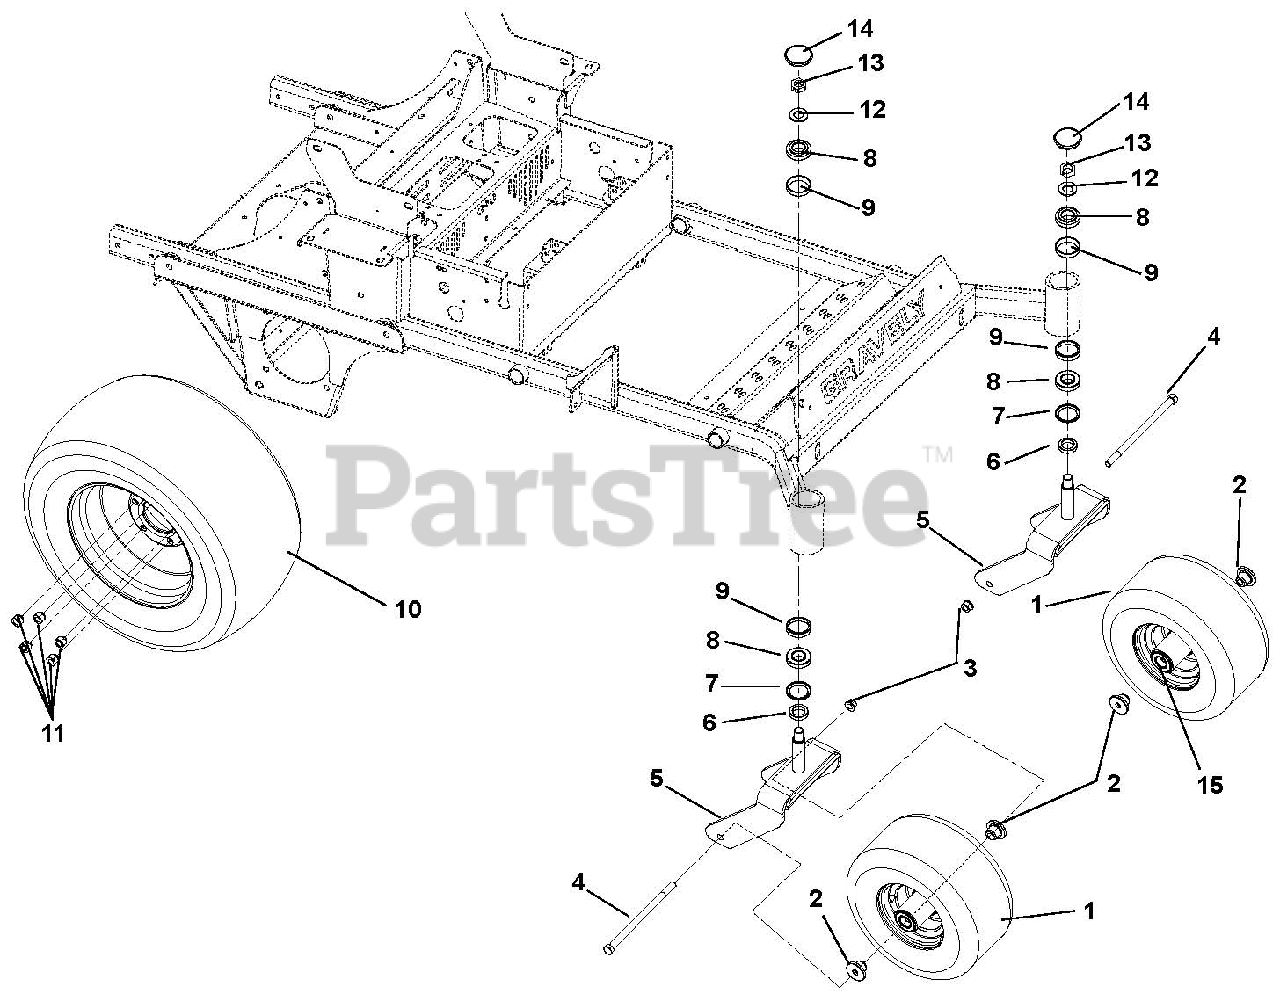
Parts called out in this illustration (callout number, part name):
1	Tire/Wheel Assembly, 15 x 6.00-6 Smooth
1	Tire, 15 x 6.00-6 Smooth
2	Spacer, Front Wheel
3	Nut, .50-13 Nyloc Flange
4	Bolt, Hex .50-13 x 9.00 Grade 5
5	Caster Fork Weldment
6	Spacer 1.258 x 1.75 x .550
7	Seal, Oil 1.75 x 2.332 x .312
8	Bearing, Cone 1.25 x .66
9	Bearing, Cup 2.328 x .465
10	Tire/Wheel Assembly, 24 x 11.50-12 x
10	Tire, 24 x 11.50-12
10	Tire/Wheel Assembly, 23 x 10.5-12
10	Tire, 23 x 10.00-12
11	Nut, Wheel .50-20 13/16 Across Flats Automotive Type
12	Washer, Flat Steel .812 x 2.00 x .148
13	Nut, Jam Center Lock .75-16
14	Cap, Dust
15	Bearing, 25 mm ID x 52 mm OD x 15 mm
